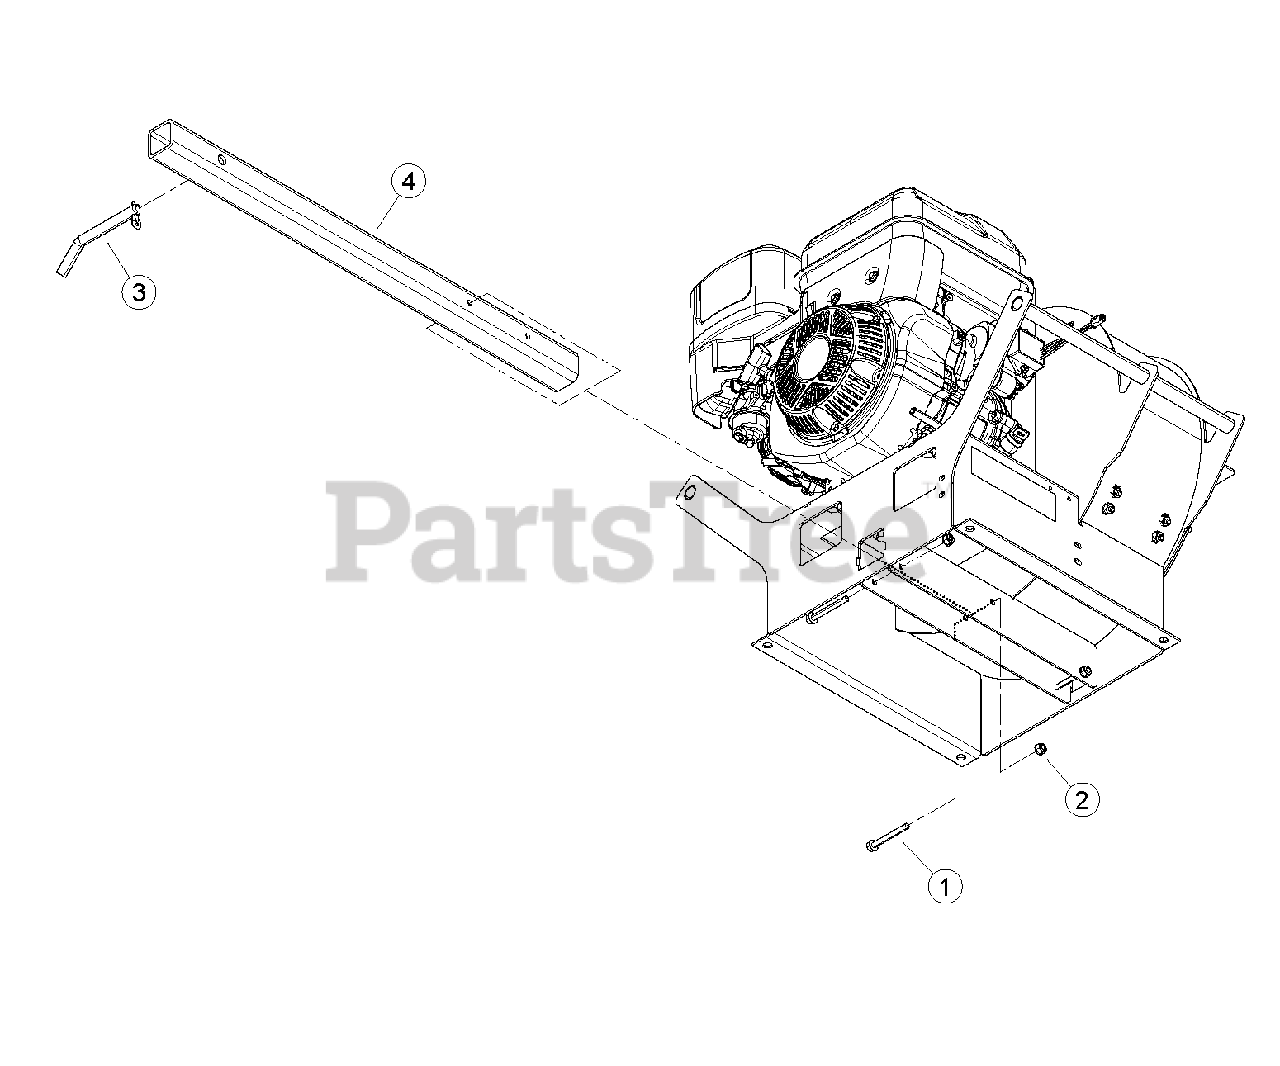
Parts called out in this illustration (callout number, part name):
1	BOLT, 5/16 X 2-3/4 FLANGE NC
2	NUT, 5/16-18 NYLOCK FLANGE
3	PIN, HITCH BENT ARM 5/8
4	TUBE, HITCH
